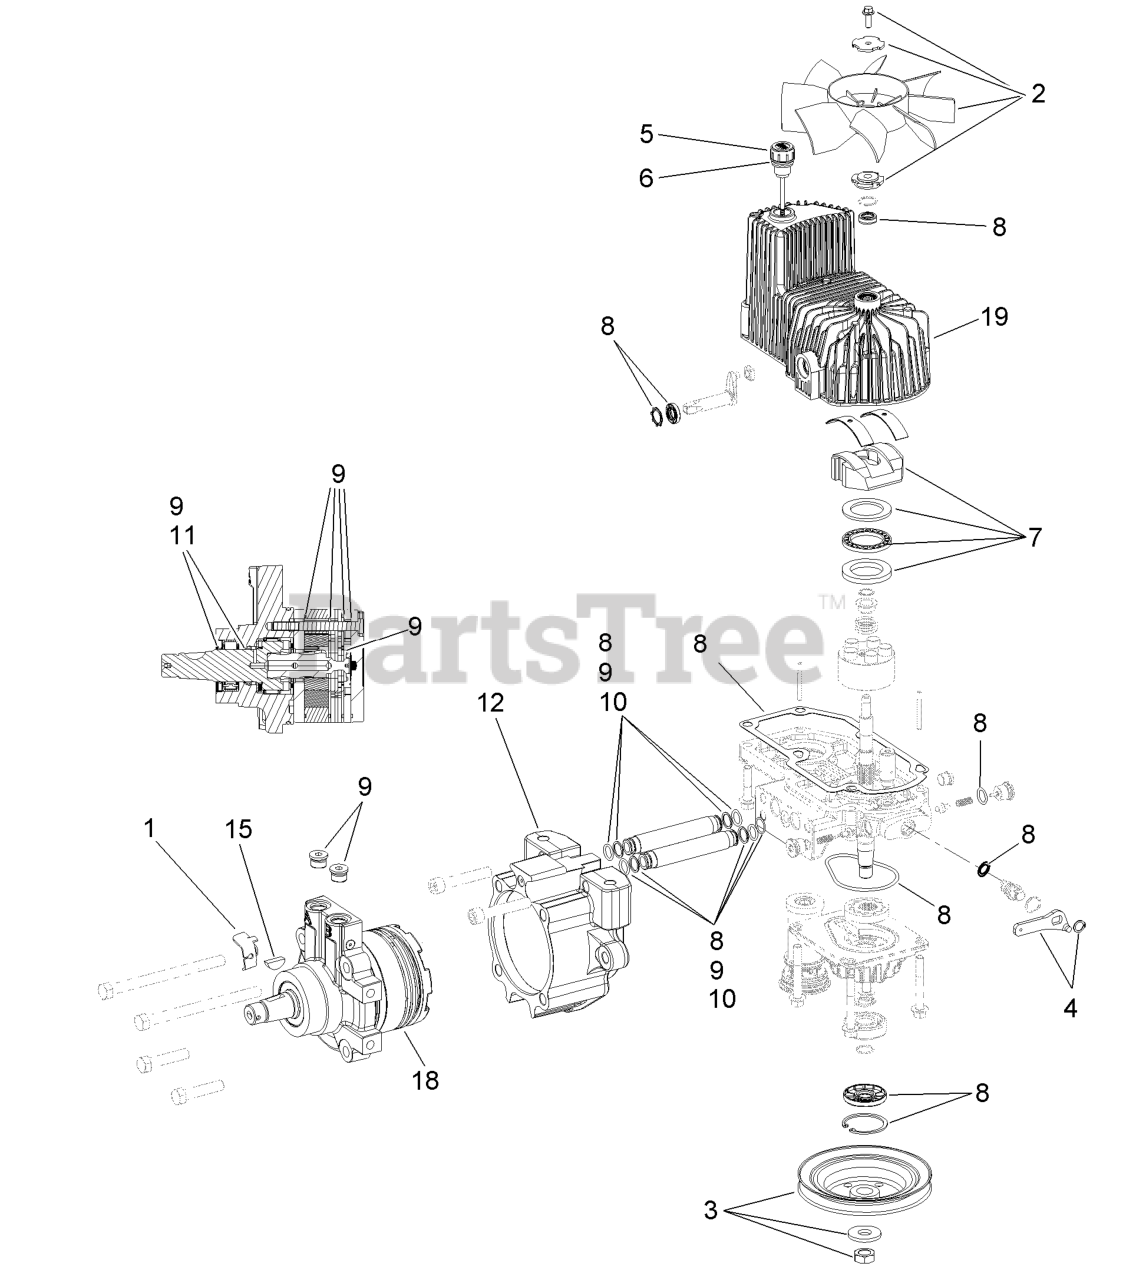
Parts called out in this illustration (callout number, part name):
1	BRACKET-ANCHOR, CABLE
2	FAN KIT
3	PULLEY KIT
4	HANDLE-BYPASS VALVE, HYDRO
5	DIPSTICK-HYDRO W/GASKET
6	GASKET-DIPSTICK, HYDRO
7	SWASH BLOCK KIT
8	PUMP SEAL KIT
9	MOTOR SEAL KIT
10	TUBE SEAL KIT
11	OUTPUT SHAFT SEAL KIT
15	KEY-WOODRUFF
19	HOUSING-HYDRO, LH
